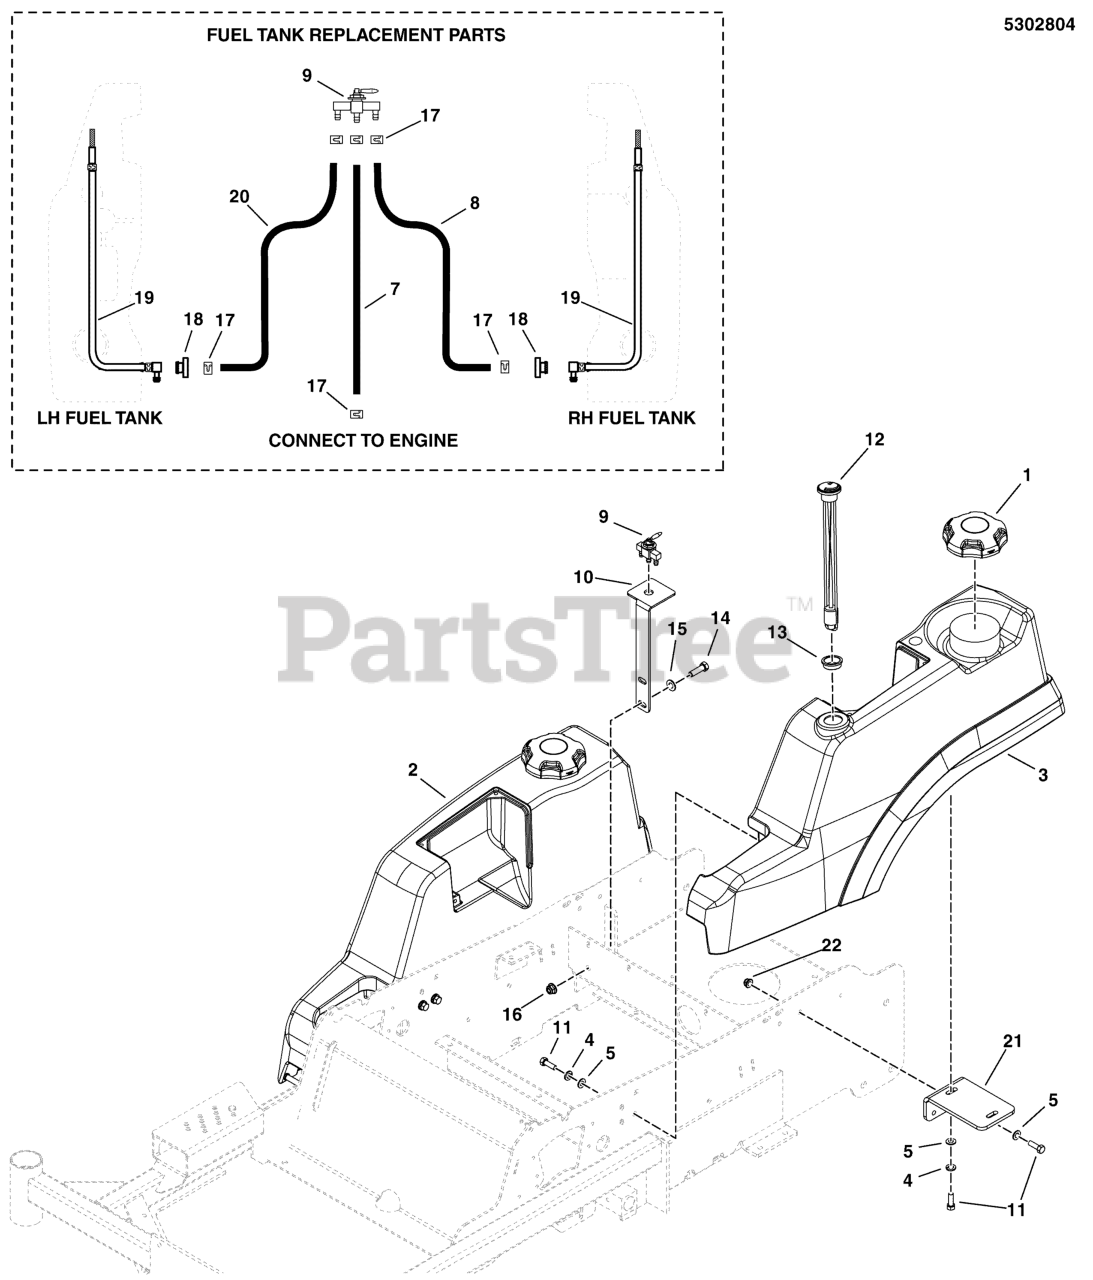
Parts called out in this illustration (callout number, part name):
1	FUEL CAP, 3-1/2", MANAGED VENT OUT, 12"
2	TANK, FUEL, SNAP & SNP PRO - RH
3	TANK, FUEL, SNAP & SNP PRO - LH
4	WASHER, 5/16 LOCK CZ
5	WASHER, 5/16" SAE
7	HOSE, FUEL, 1/4 IN, LW PRMTN, 16" LONG
8	HOSE, FUEL, 1/4 IN, LW PRMTN, 24" LONG
9	VALVE, FUEL, STR. OUTLET
10	FUEL, VALVE BRACKET - BLK
11	BOLT, 5/16-18 X 1 GD5 YZ
12	FUEL GAUGE, 10" (SV)
13	GROMMET, FUEL GAUGE (SV)
14	BOLT, 3/8-16 X 1-1/2" GD5 CZ
15	WASHER, 3/8 SAE
16	NUT, 3/8-16 HEX NYLOCK FLANGE
17	CLAMP, HOSE, EXTERNAL, 1/2 - RED
18	BUSHING-FUEL TANK RED RUBBER
19	PICKUP TUBE ASSEMBLY, FUEL LINE (SV)
20	HOSE, FUEL, 1/4 IN, LW PRMTN, 26" LONG
21	MOUNT, TANK, REAR - BLK
22	NUT, 5/16-18 HEX NYLOCK FLANGE
